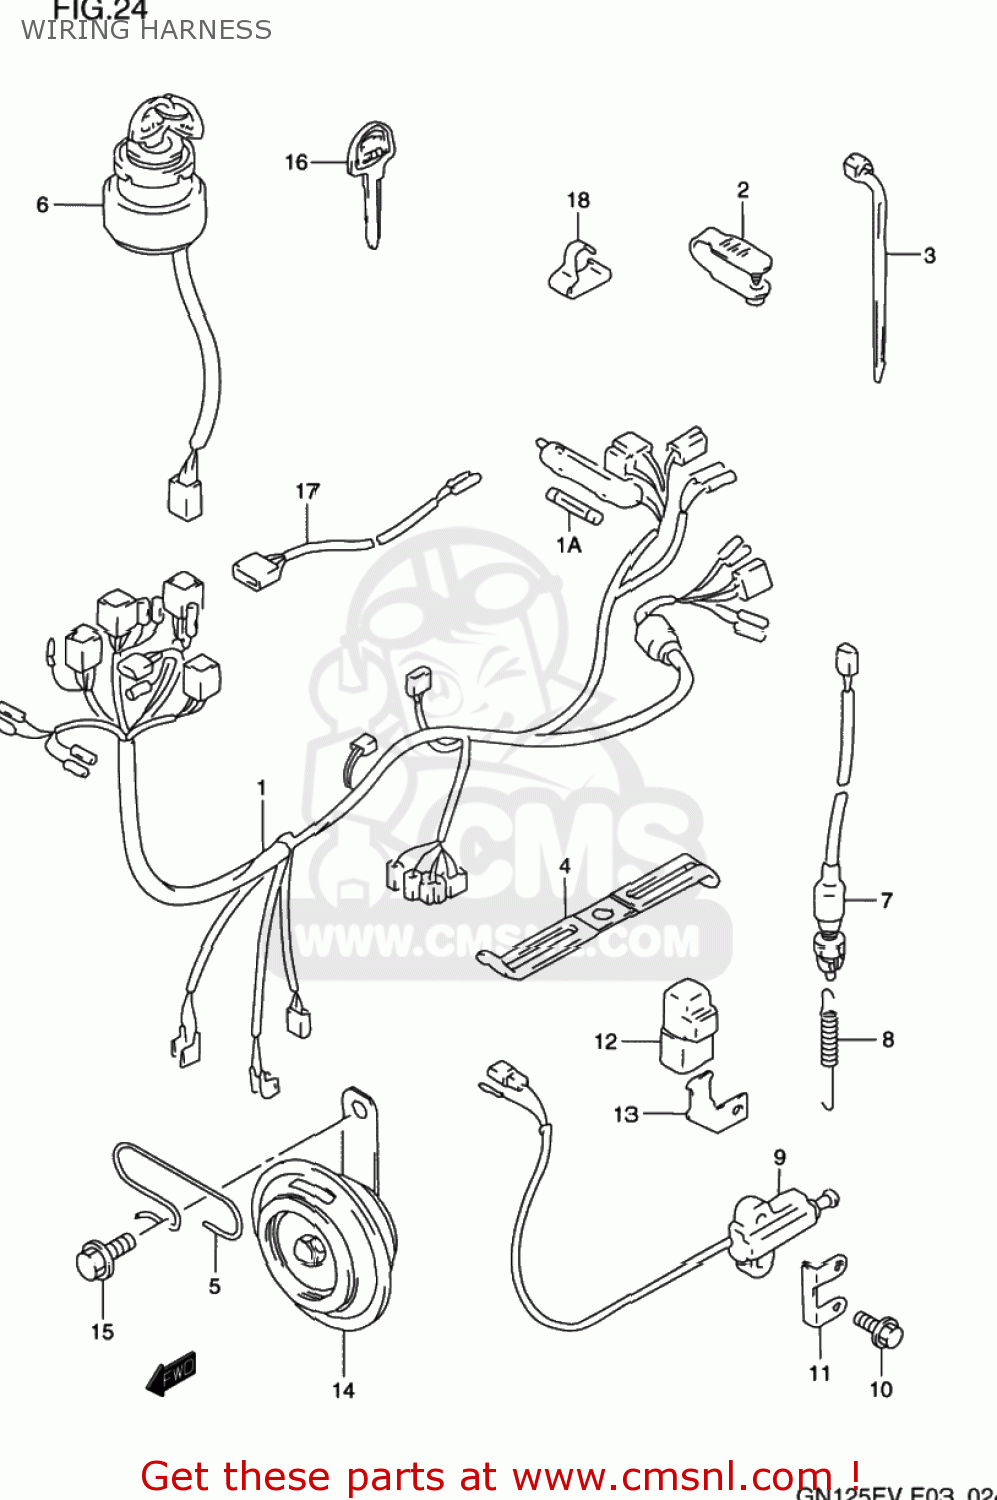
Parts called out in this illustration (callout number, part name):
1	HARNESS,WIRING
1A	FUSE(15A)
2	CLAMP,L:88
3	CLAMP L:165
4	CLAMP,STARTER MOTOR LEAD
5	CLAMP,WIRING HARNESS
6	SWITCH ASSY,IGNITION
7	SWITCH ASSY,STOP LAMP
8	SPRING
9	SWITCH ASSY,SIDE STAND
10	BOLT
11	PROTECTOR,SIDE STAND SWITCH
12	RELAY ASSY
13	BRACKET,SIDE STAND RELAY
14	HORN ASSY
15	BOLT
16	KEY,BLANK
17	WIRE,CLUTCH SWITCH LEAD
18	HOLDER,FUSE CASE
